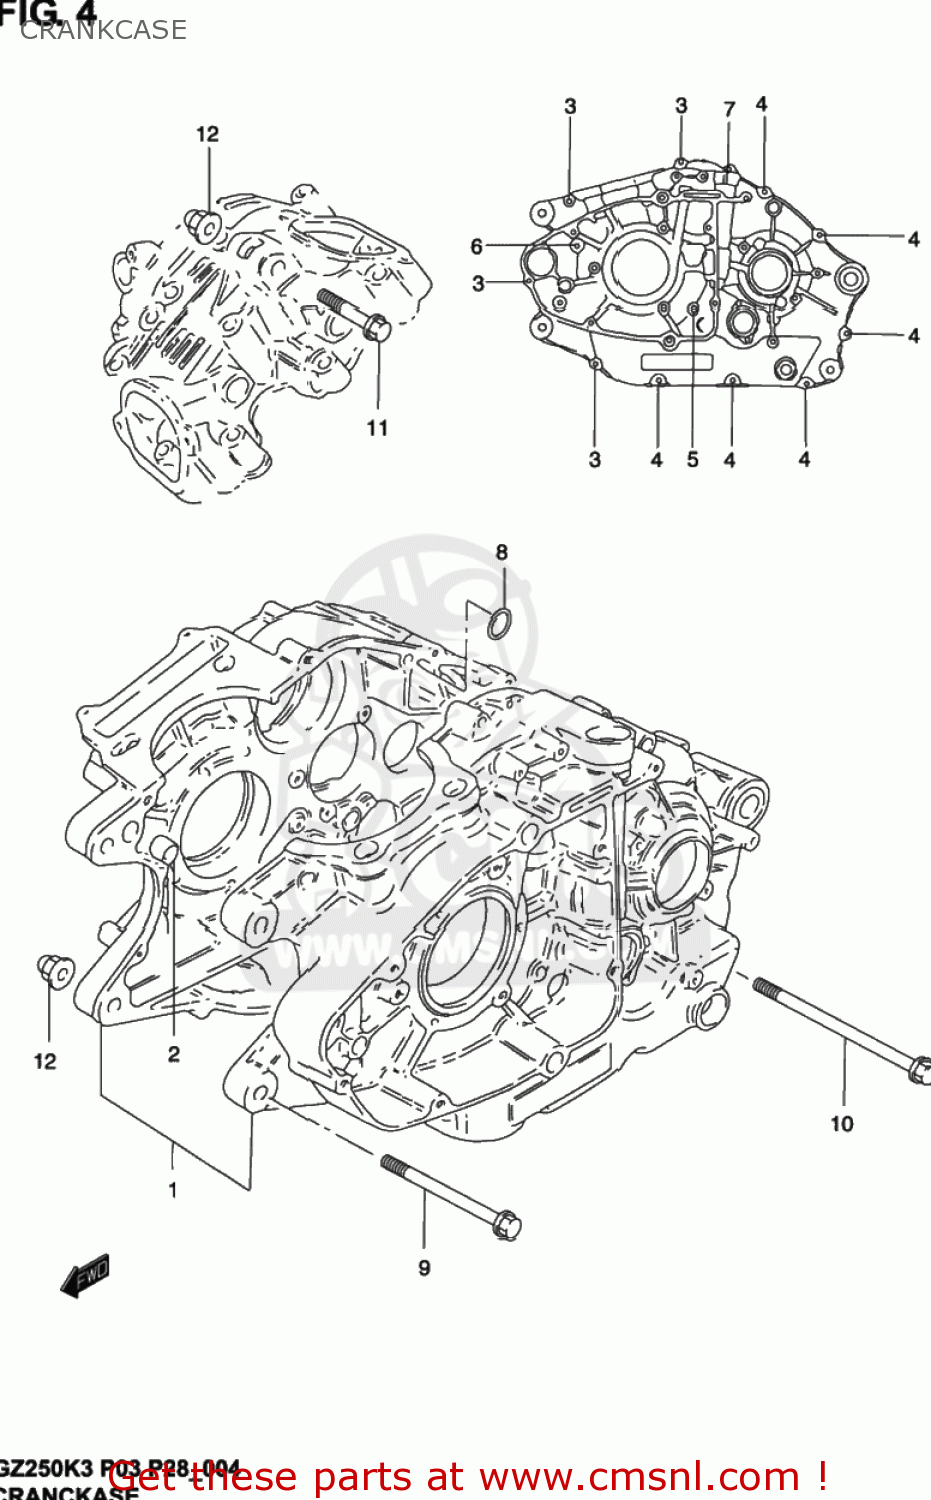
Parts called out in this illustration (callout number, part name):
1	CRANKCASE SET MODEL K3
2	PIN
3	BOLT
4	BOLT
5	BOLT
6	BOLT
7	BOLT
8	O RING(D:1.9,ID:9.8)
9	BOLT(8X67)
10	BOLT(8X100)
11	BOLT(8X50)
12	NUT
